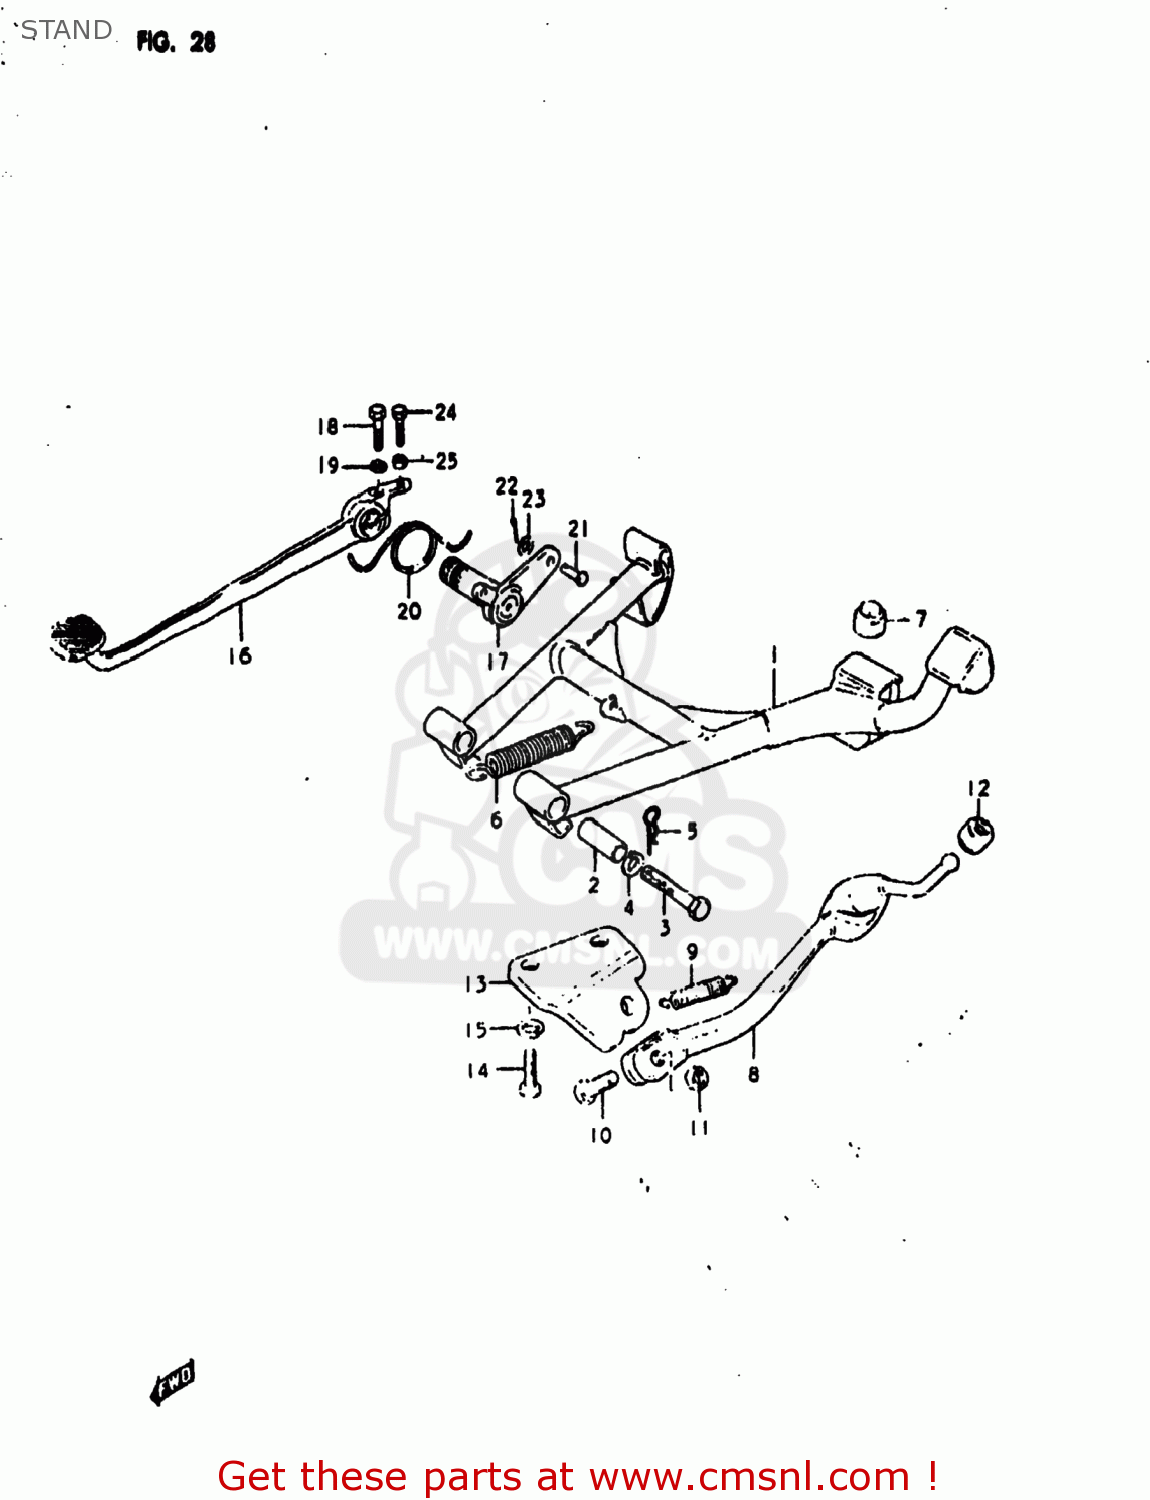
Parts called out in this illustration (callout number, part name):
1	STAND,CENTER
2	SPACER(10X16X38.8)
3	BOLT
4	LOCK WASHER
5	CLIP
6	SPRING
7	CUSHION
8	STAND,PROP
9	SPRING
10	BOLT(10X30)
11	NUT
12	CUSHION
13	BRACKET,SIDE STAND
14	BOLT
15	LOCK WASHER
16	PEDAL,BRAKE
17	ARM,BRAKE PEDAL
18	BOLT
19	LOCK WASHER
20	SPRING
21	PIN
22	PIN
23	WASHER
24	BOLT
25	NUT
